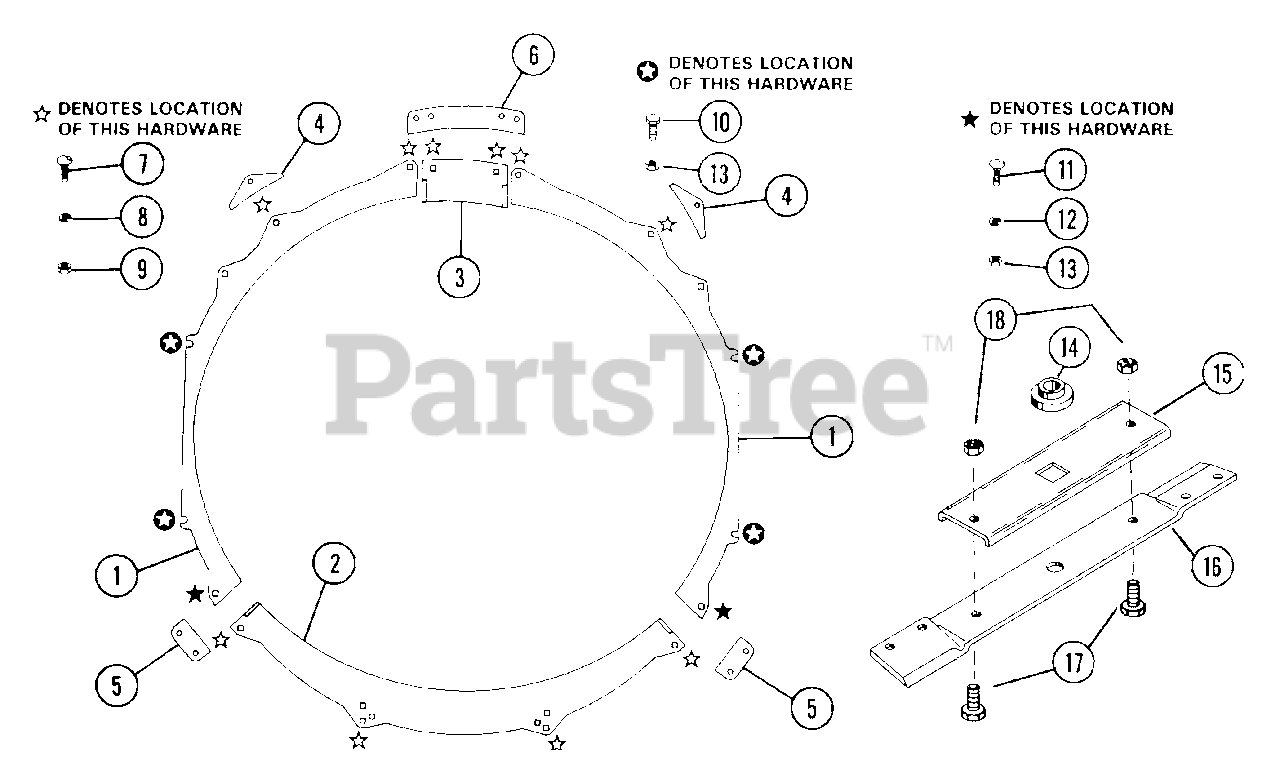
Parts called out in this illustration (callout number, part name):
1	SIDE FLANGE
2	BACK FLANGE
3	FRONT CLAMP
4	SIDE CLAMP
5	JOINT CLAMP
6	FRONT CLAMP
7	BLT-RDHDSQNK .25-20X.62 PL
8	WSHR-LK .313X.093 MED HICLR
9	NUT-LK-CTR .250-20 PL
10	BLT-HEX .31-18X.63 PL GR 2
11	BLT-RDHDSQNK .312-18X.62SHTPL
12	WSHR-LK .375X.115 HVY PL
13	NUT-LK .312-18 GR A PL
14	RETAINER HUB
15	BLADE TRAY
16	MOWER BLADE 28
17	BLT-HEX .38-16X.75 PL GR5
18	NUT-LK TOP .375-16 GR C YWZC
